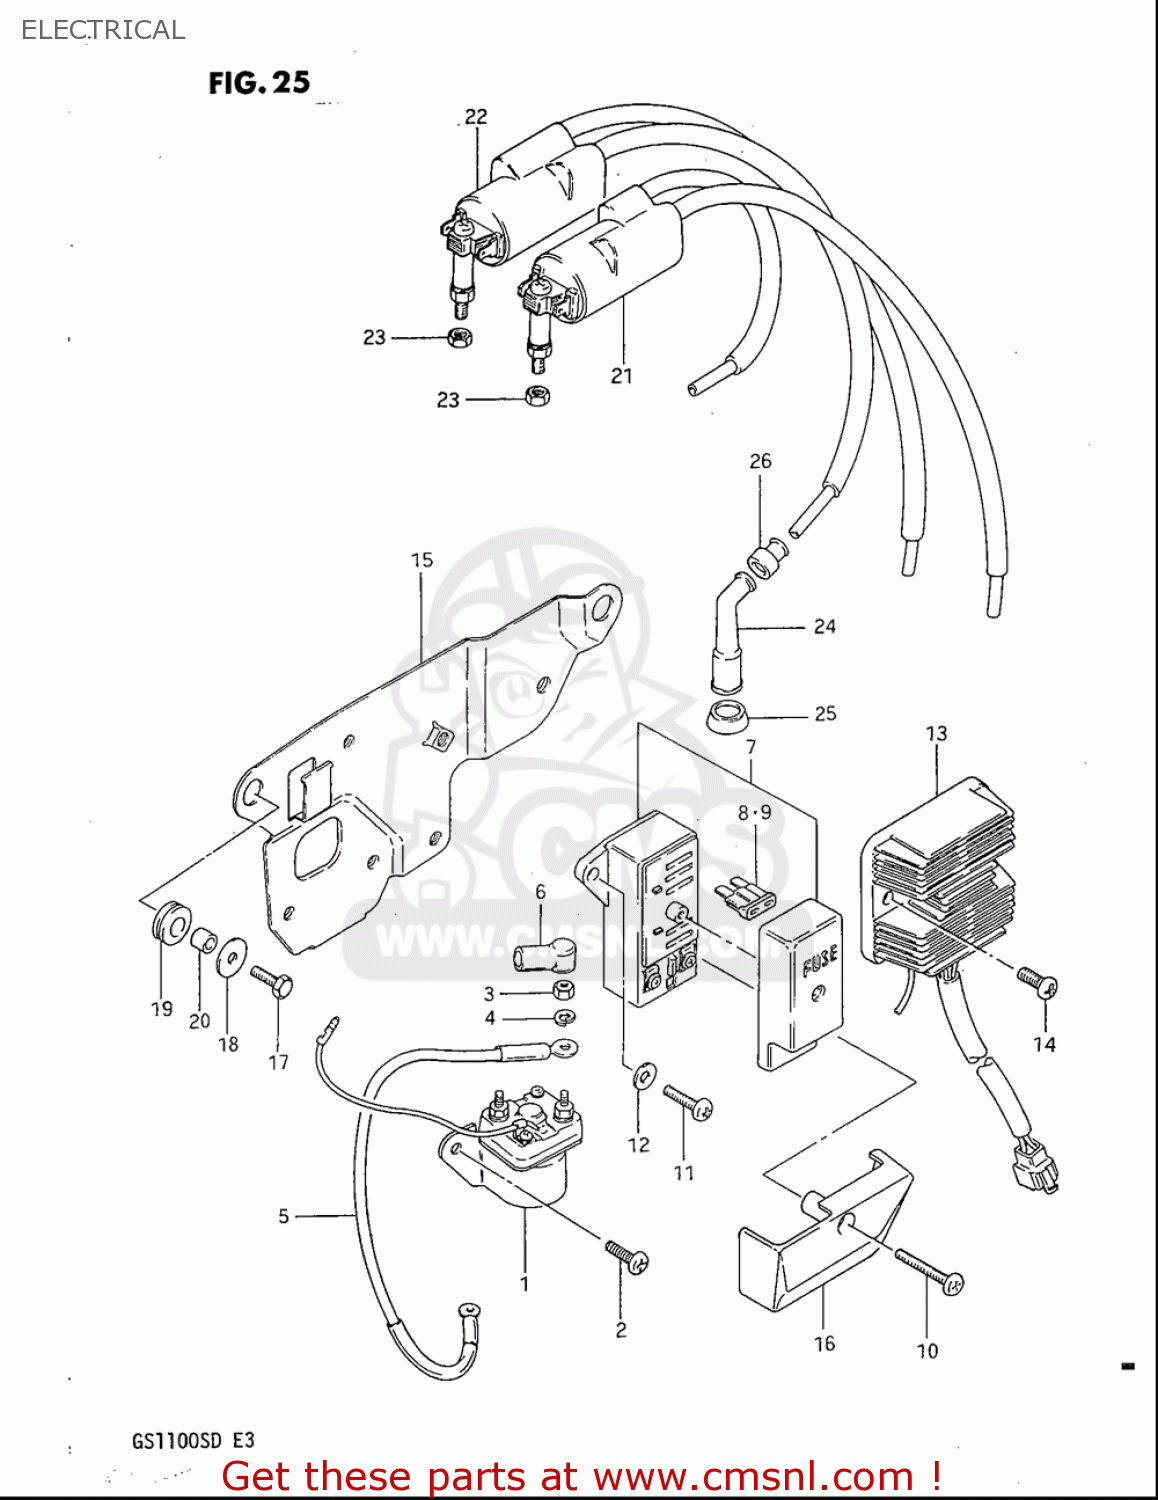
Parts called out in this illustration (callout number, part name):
1	RELAY ASSY,STARTING MOTOR
2	SCREW
3	NUT
4	WASHER,LOCK
5	LEAD WIRE,BATTERY(-)
6	CAP,STARTER MOTOR LEAD
7	BOX ASSY,FUSE
8	FUSE(10A)
9	FUSE(15A)
10	SCREW
11	SCREW
12	WASHER
13	RECTIFIER ASSY
14	SCREW
17	BOLT
18	WASHER (6.5X22X1.6)
19	CUSHION
20	SPACER,6.5X9X7
21	COIL ASSY,IGNITION
22	COIL ASSY,IGNITION
23	NUT
24	CAP ASSY,SPARK PLUG
25	SEAL,SPARK PLUG
26	SEAL,HIGH TENSION CORD
